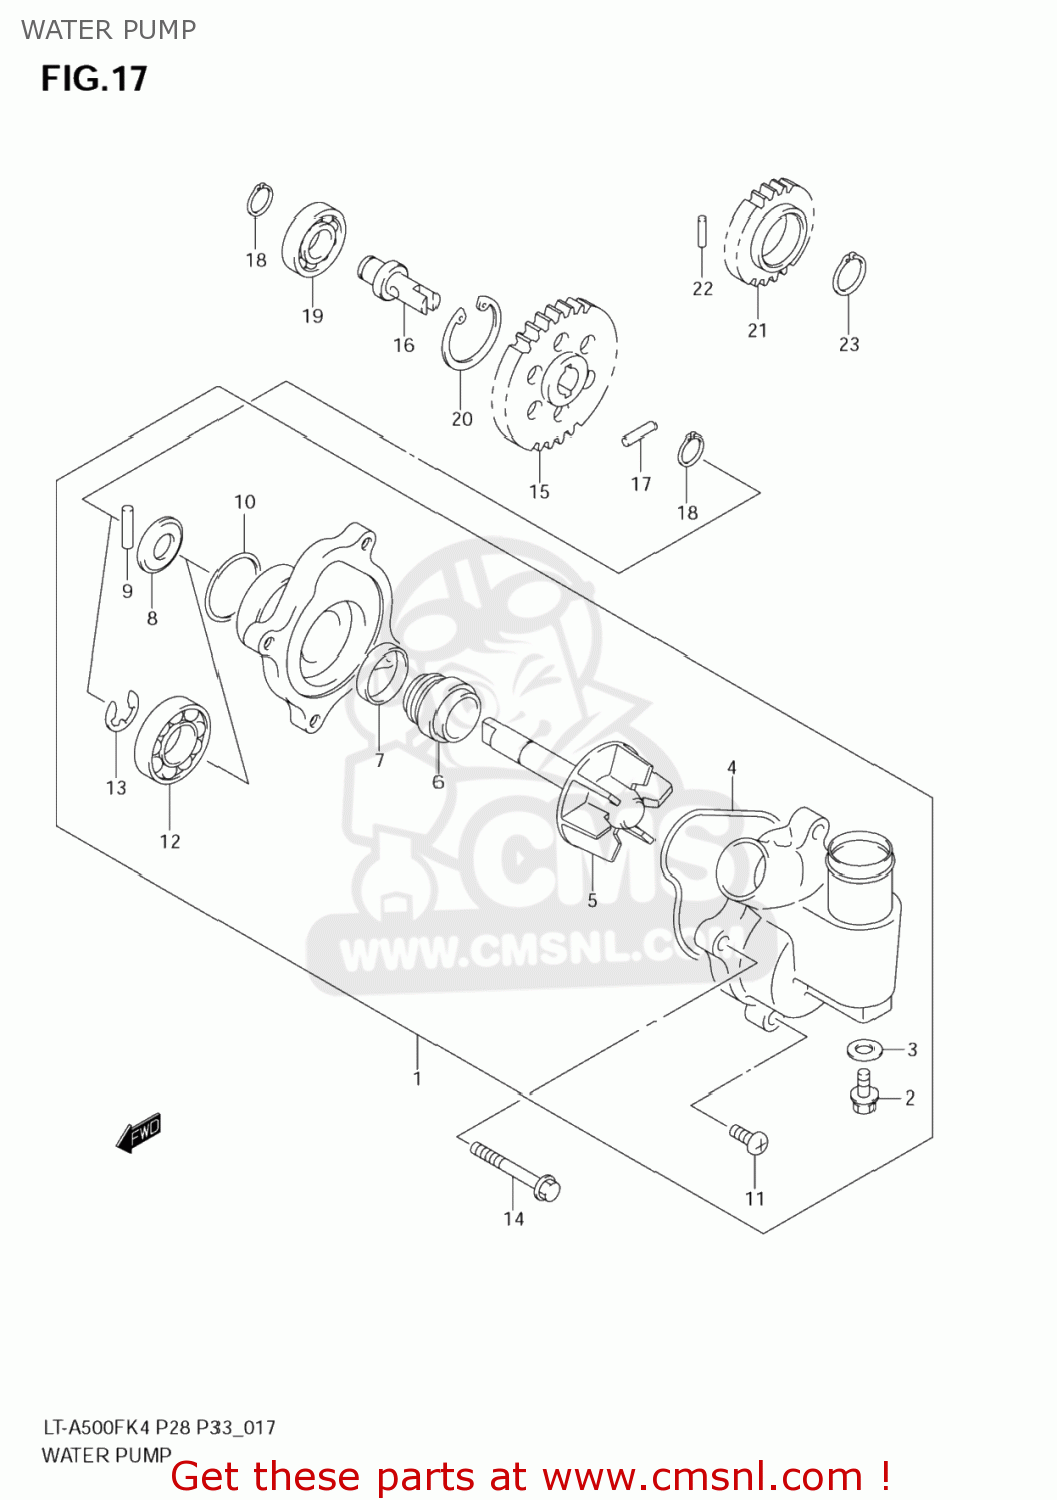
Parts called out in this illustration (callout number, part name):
1	PUMP ASSY,WATER
2	BOLT,DRAIN
3	GASKET(8.2X14X1) (NAS)
4	O RING
5	IMPELLER/SHAFT
6	SEAL,MECHANICAL
7	SEAL,OIL(10X21X5)
8	WASHER
9	PIN
10	O RING,WATER PUMP HOLDER
11	SCREW 6X16
12	BEARING(10X26X8)
13	E RING
14	BOLT
15	GEAR,OIL PUMP DRIVEN
16	SHAFT,WATER PUMP DRIVEN GEAR
17	PIN(4X15.8)
18	CIRCLIP,10MM
19	BEARING
20	CIRCLIP
21	GEAR,OIL PUMP DRIVE
22	PIN
23	CIRCLIP
